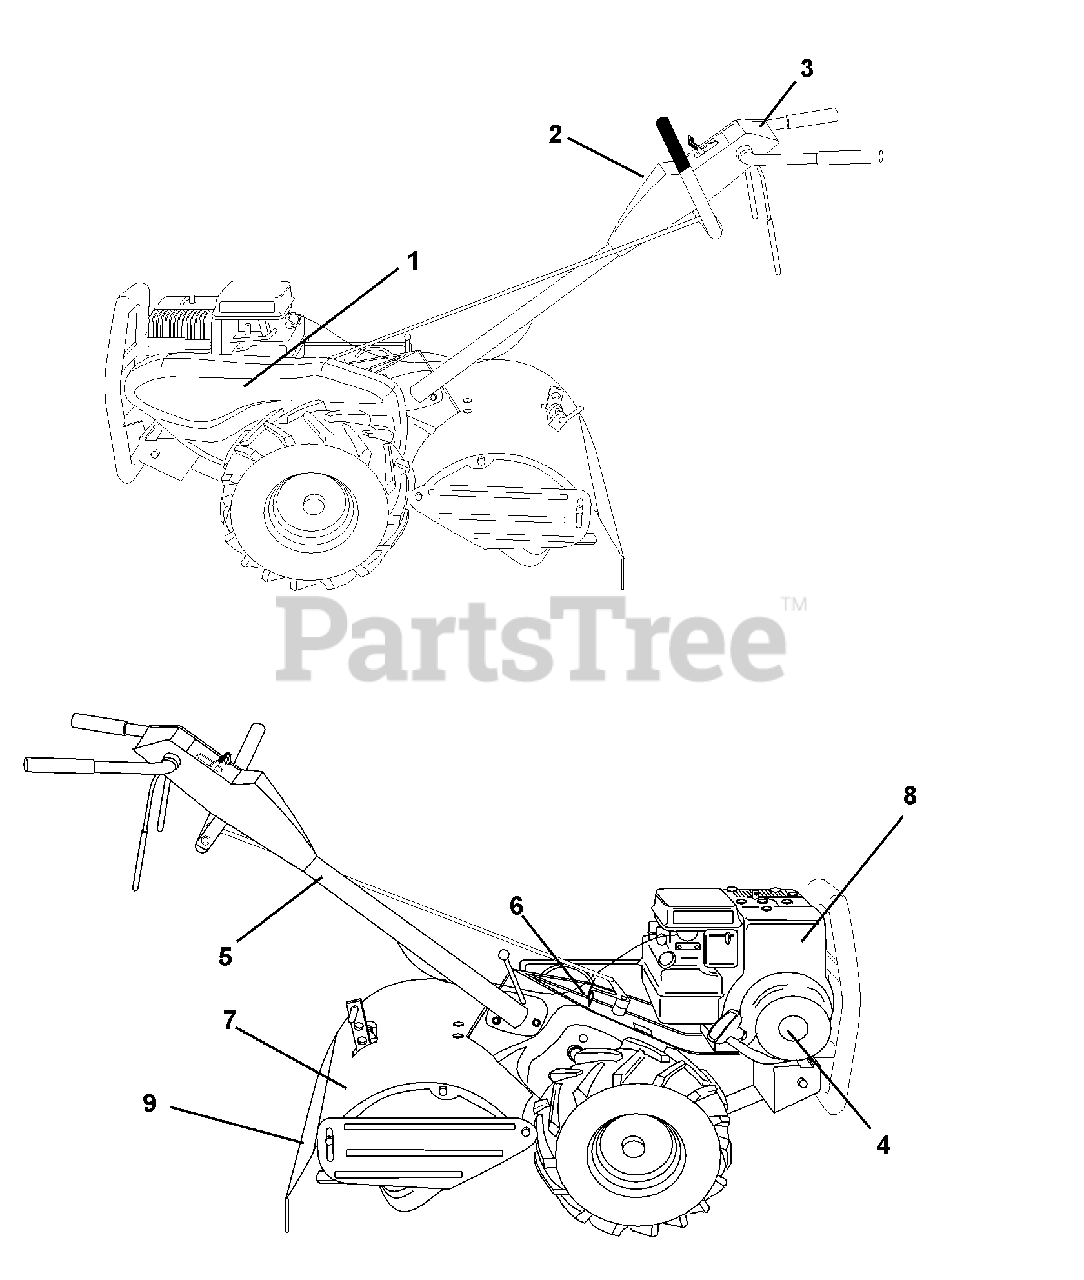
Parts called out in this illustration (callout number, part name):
1	Decal, Logo
2	Decal, Logo
3	Decal, Logo
4	Decal, 5 HP
5	Decal, Hand Placement
6	Decal, Shift Indicator
7	Decal, Warning
8	Decal, Briggs & Stratton
9	Decal, Warning, Rotating Tines
